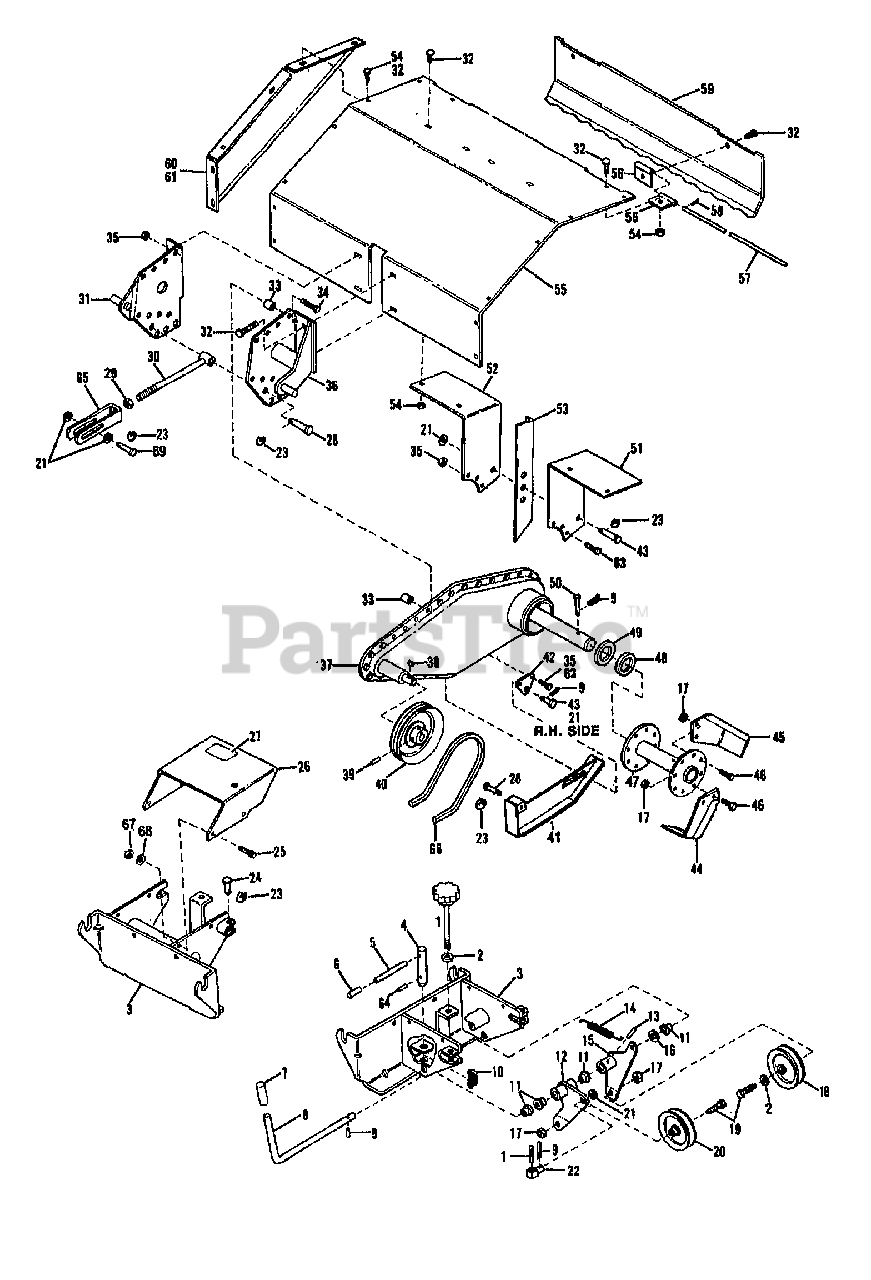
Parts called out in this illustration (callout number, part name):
1	ASSM-KNOB ADJ
2	WASHER-FLAT 3/8 SAE
4	PIN-HITCH
5	PIN-ROLL .312X4.00 ZP
6	GRIP-HANDLE
7	GRIP-HANDLE
8	SHAFT-IDLER
9	PIN-COTTER .120X1.00 ZP
10	SPRING-COMPRESSION
11	BEARING-FLANGE
12	ASSM-IDLER ARM
13	PIN-ROLL .188X1.0
15	ASSM-IDLER ARM
16	WASHER-1.305X.649X.098 ZP
17	NUT-LOCK 3/8-16
18	PULLEY-IDLER
19	SCR-HH 3/8-16X1.75 G5 ZP
20	PULLEY-IDLER ZP
21	WASHER-1.06X.531X.1 ZP
22	BLOCK-PIVOT
23	RING-CIRCLE COTTER
24	PIN-CLEVIS .5X1.437 ZP
25	SCR-HH 1/4-20X.75 G5 ZP
26	ASSM-BELT COVER W/DECAL
27	DECAL-OPEI CAUTION
28	PIN-CLEVIS .5X2.5 ZP
29	NUT-HEX/JAM 5/8-18 ZP
31	PLATE-MOUNTING CHAIN CASE
32	SCR-CARR 5/16-18X.75
33	SPACER-.384X.268X.788 ZP
34	SCR HH 1/4-20X2.5 G5 ZP
35	NUT-HT LK 1/4-20
36	PLATE-MOUNTING LH
37	ASSM-CHAINCASE
38	KEY-WOODRUFF .188X.75
39	SCR-SET HXSKT 5/16-18X.38
40	SHEAVE-DRIVE
41	ASSY DEPTH SHOE
43	PIN-CLEVIS .5X1.06 ZP
46	SCR-HH 3/8-16X1.0 G5 ZP
47	ASSM-TINE HOLDER
48	SEAL-DUST (OUTER)
49	SEAL-DUST 2.31 DIA
50	PIN-CLEVIS .437X2.06 ZP
51	SUPT-HOOD LH
52	SUPT-HOOD RH
54	NUT-HFLK 5/16-18 ZP
55	HOOD-TINE TOP
56	HINGE-HOOD
57	PIN-HINGE
58	PIN-COTTER .09X.75 ZP
60	COVER-SIDE HOOD RH
61	COVER-SIDE HOOD LH
63	SCR-HH 1/4-20X1.0
64	PIN-ROLL .125X1.25
65	ASSM-CLEVIS
67	NUT-HEX 1/4-20 ZP
68	WASHER-LK .25 ZP
69	PIN-CLEVIS .5X1.75 ZP
